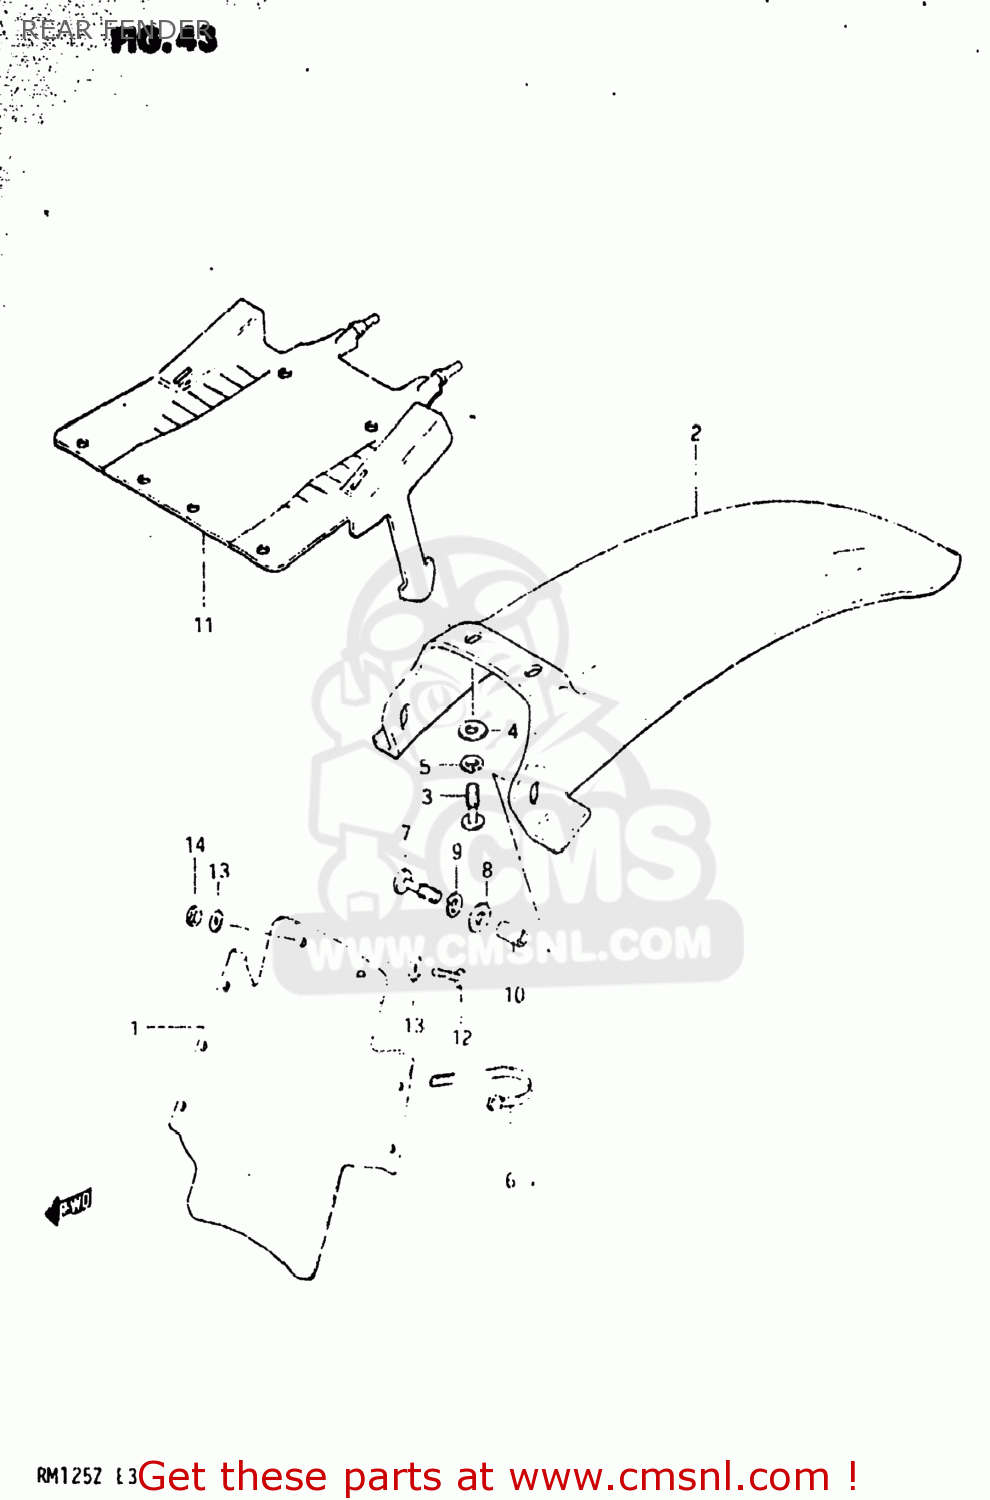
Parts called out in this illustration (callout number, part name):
1	FENDER,REAR
2	FENDER,REAR
3	SCREW
4	WASHER (6.5X20X1.2)
5	LOCK WASHER
6	CLAMP
7	SCREW
8	WASHER (6.5X20X1.2)
9	LOCK WASHER
10	SPACER
11	GUIDE,RR FENDER MUD
12	SCREW
13	WASHER
14	NUT
